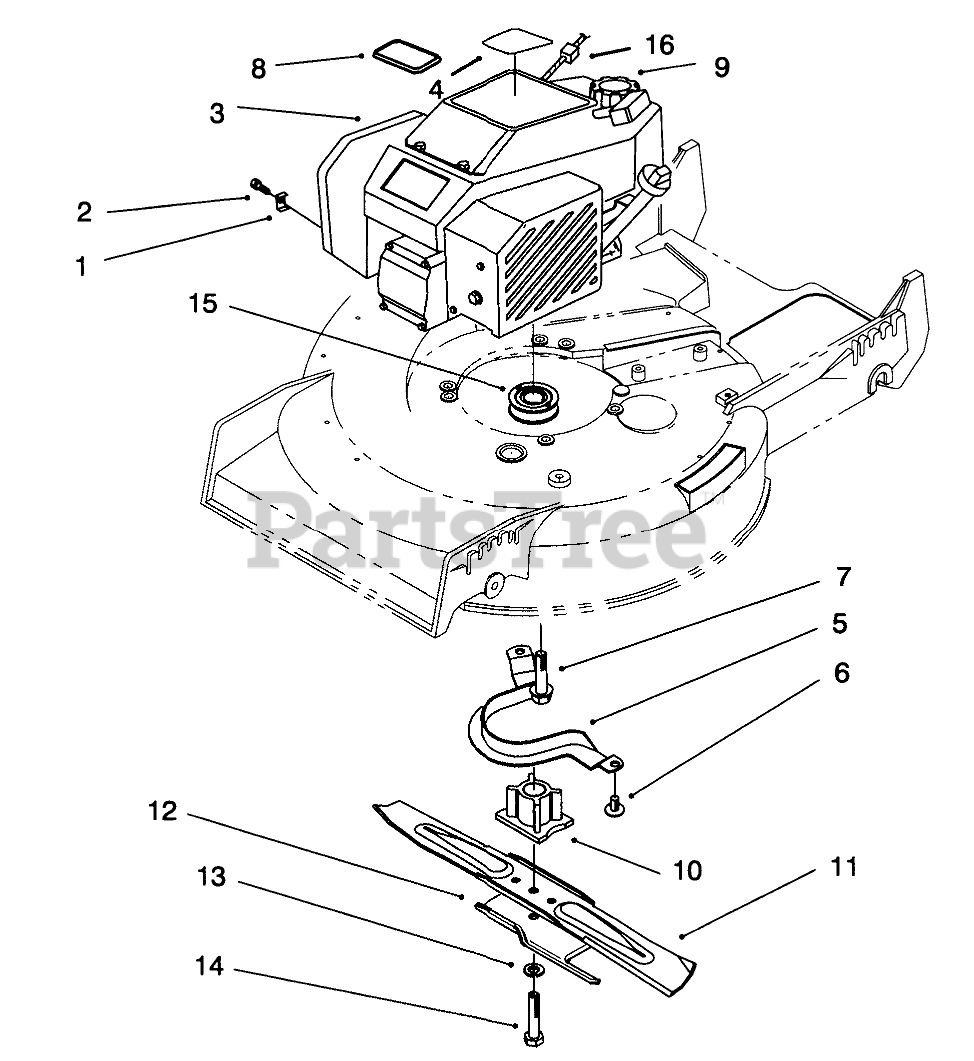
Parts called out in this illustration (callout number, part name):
1	CLAMP-CASING
2	CLAMP SCREW F/W ENGINE
3	ASM-ENGINE,GTS150 NC
4	DECAL - ENGINE
5	Guide-Belt
6	SCREW-HWHTF
7	SCREW-HWH
8	PLATE-LOGO
9	ASSY FUEL CAP
10	BLADE RETAINER
11	Blade
12	Accelerator
13	WASHER-LOCK
14	SCREW-BLADE
15	PULLEY-DRIVE, ZONE START
16	STOP-ROPE
